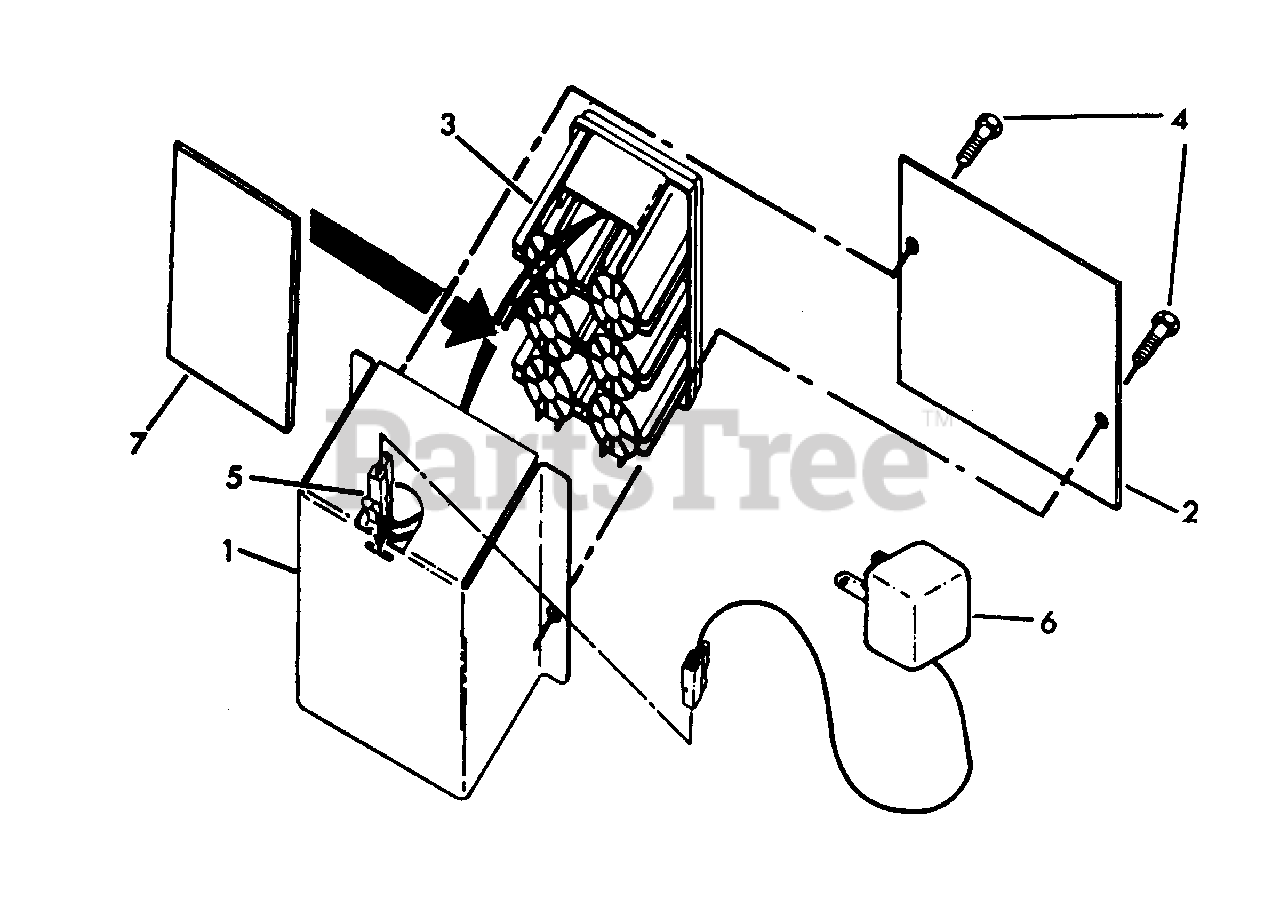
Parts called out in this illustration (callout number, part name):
1	Battery Bracket (AYP part number)
2	Battery Cover (AYP part number)
3	Battery (AYP part number)
4	Hex Washer Head Screw #10-24 x .625 (AYP part number)
5	Connector Mounting Clip (AYP part number)
6	Battery Charger (AYP part number)
7	Battery Pad (AYP part number)
